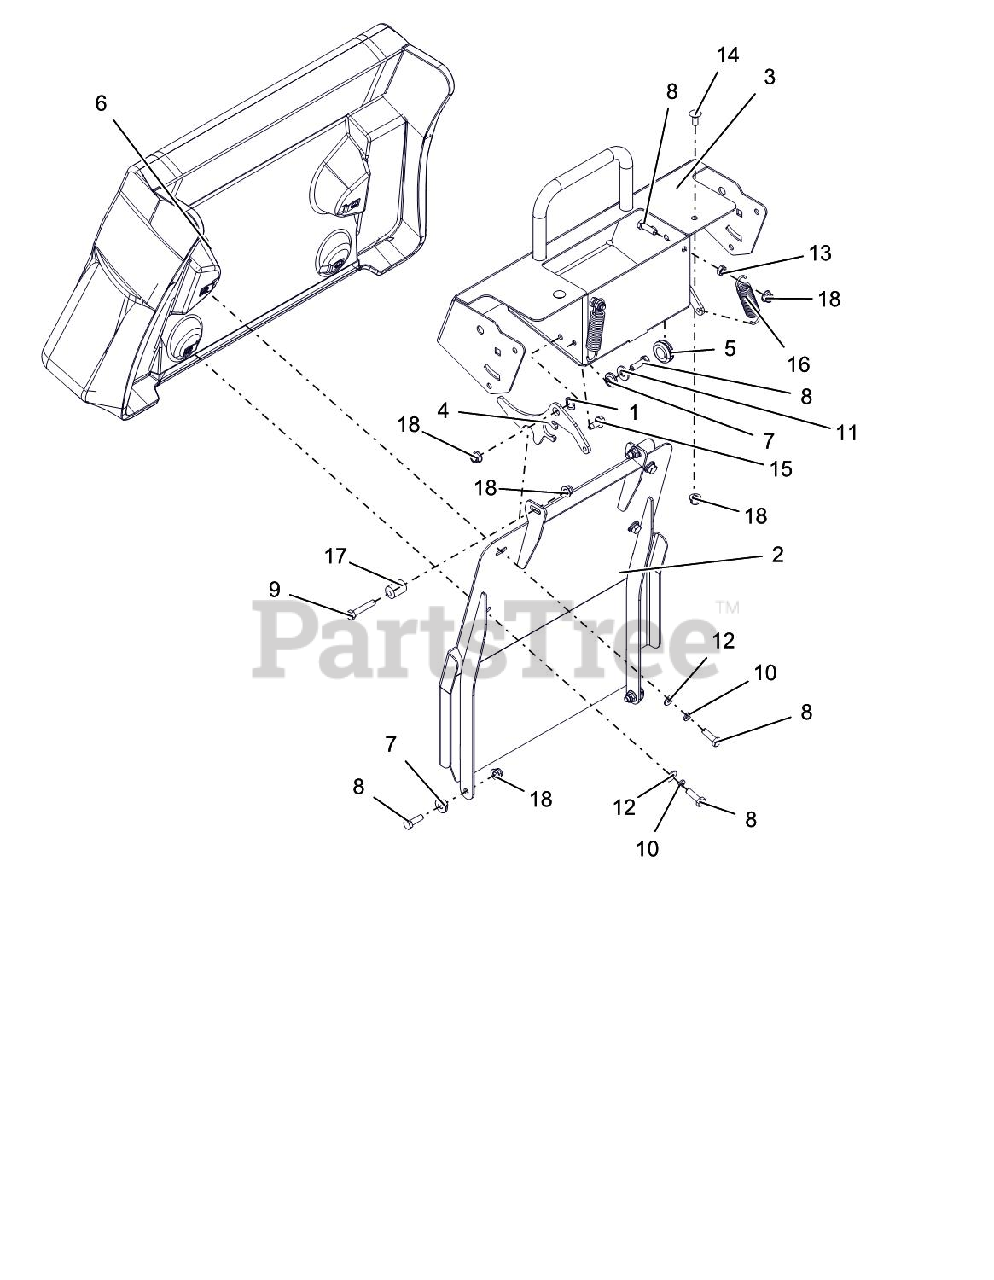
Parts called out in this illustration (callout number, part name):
1	WAVE WASHER .531X.781X.125FH
2	WLDMT, PAD MOUNT
3	WLDMT, CONTROL PANEL PROSTANCE
4	LATCH, PAD MOUNT
5	GROMMET, SPLIT RUBBER
6	PAD, PRO-STANCE OPERATOR
7	BSHG-FLG .32X.500X.344X.880
8	@BLT-HEX .31-18X1.00 GR5 YWZC
9	@BLT-HEX .31-18X1.75 GR5 YWZC
10	@WSHR-LK .31X.078 REG YWZC
11	@WSHR-FL-STL.38X.875X.083 YWZC
12	@WSHR-FL-STL.312X.734X.065 YWZ
13	@NUT-LK-CTR-JAM .31-18 YWZC
14	@BLT-RDHDSQNK .31-18X.75 G5YZ
15	@SCR-TAP .31-18X.75 HWH TR YWZ
16	SG-TENS .105X.812X3.88 WLD 15
17	ECCENTRIC
18	@NUT-LK-NYL-FLG .31-18 YWZC
